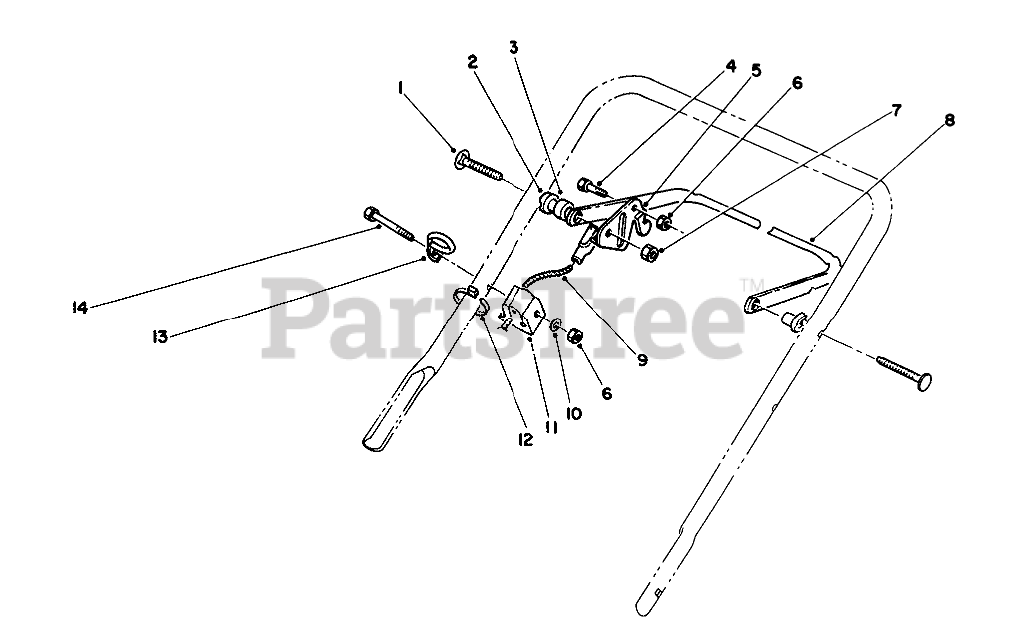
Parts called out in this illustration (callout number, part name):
1	5/16-18 X 2 HNDLE SCREW
2	SPACER-SUPPORT
3	SPACER-NYLON
4	SCREW-HH
5	LEVER-CONTROL
6	NUT-LOCK, NI
7	NUT-LOCK, NI
8	Bar-Control
9	OBS BRAKE CONTROL
10	WASHER-FLAT
11	SUPPORT-CABLE
12	TIE-CABLE
13	Guide
14	SCREW-HH
